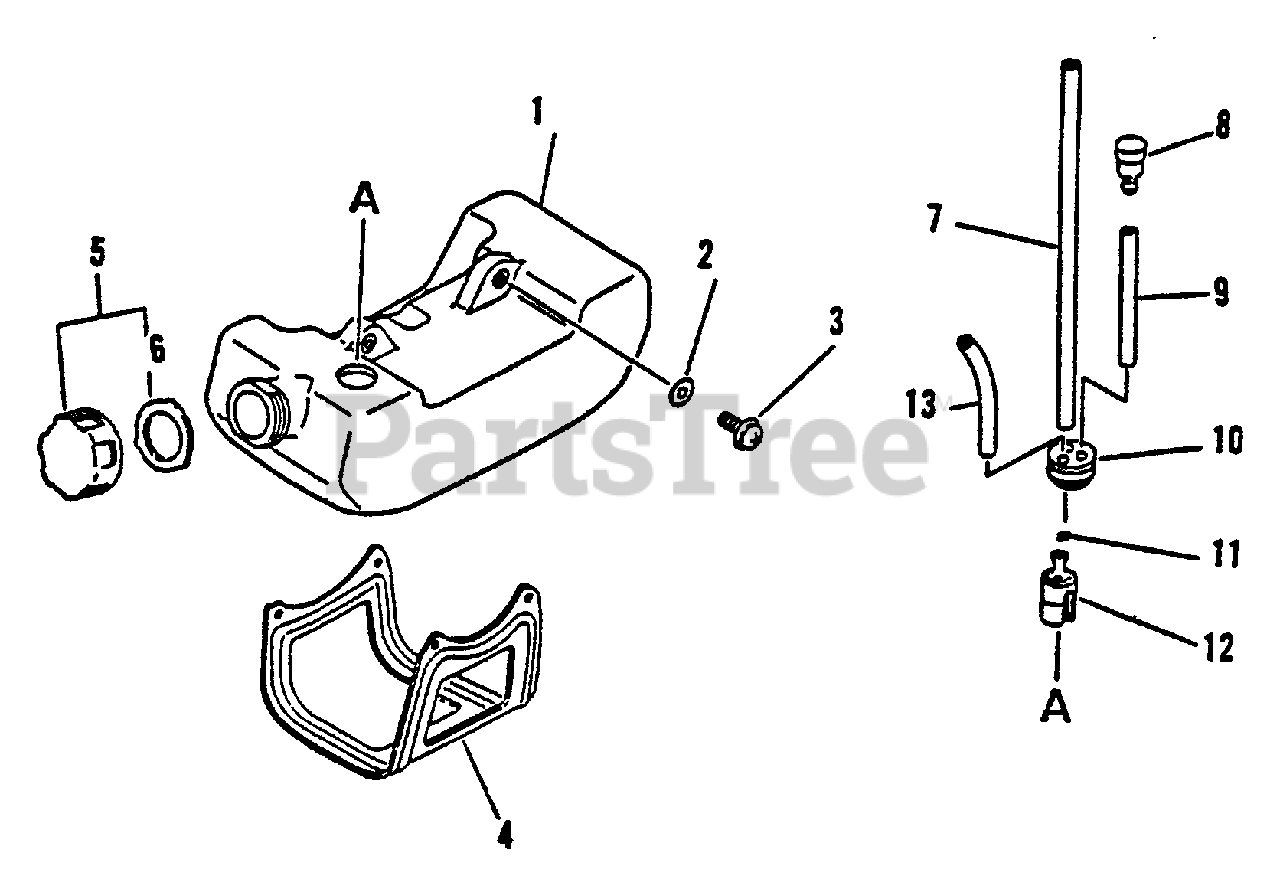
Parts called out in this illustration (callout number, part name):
1	TANK, FUEL
2	WASHER 5.5×12×0.8
3	SCREW 5×16
4	GUARD, FUEL TANK
5	CAP ASSY
6	GASKET, FUEL CAP
7	PIPE, FUEL 3x-5x-180
8	VENT ASSY
9	PIPE, FUEL 3x-5x-70 BLACK
10	GROMMET, FUEL
11	CLIP 6 MM
12	FILTER, FUEL
13	PIPE, FUEL 3×6×80 CLEAR
